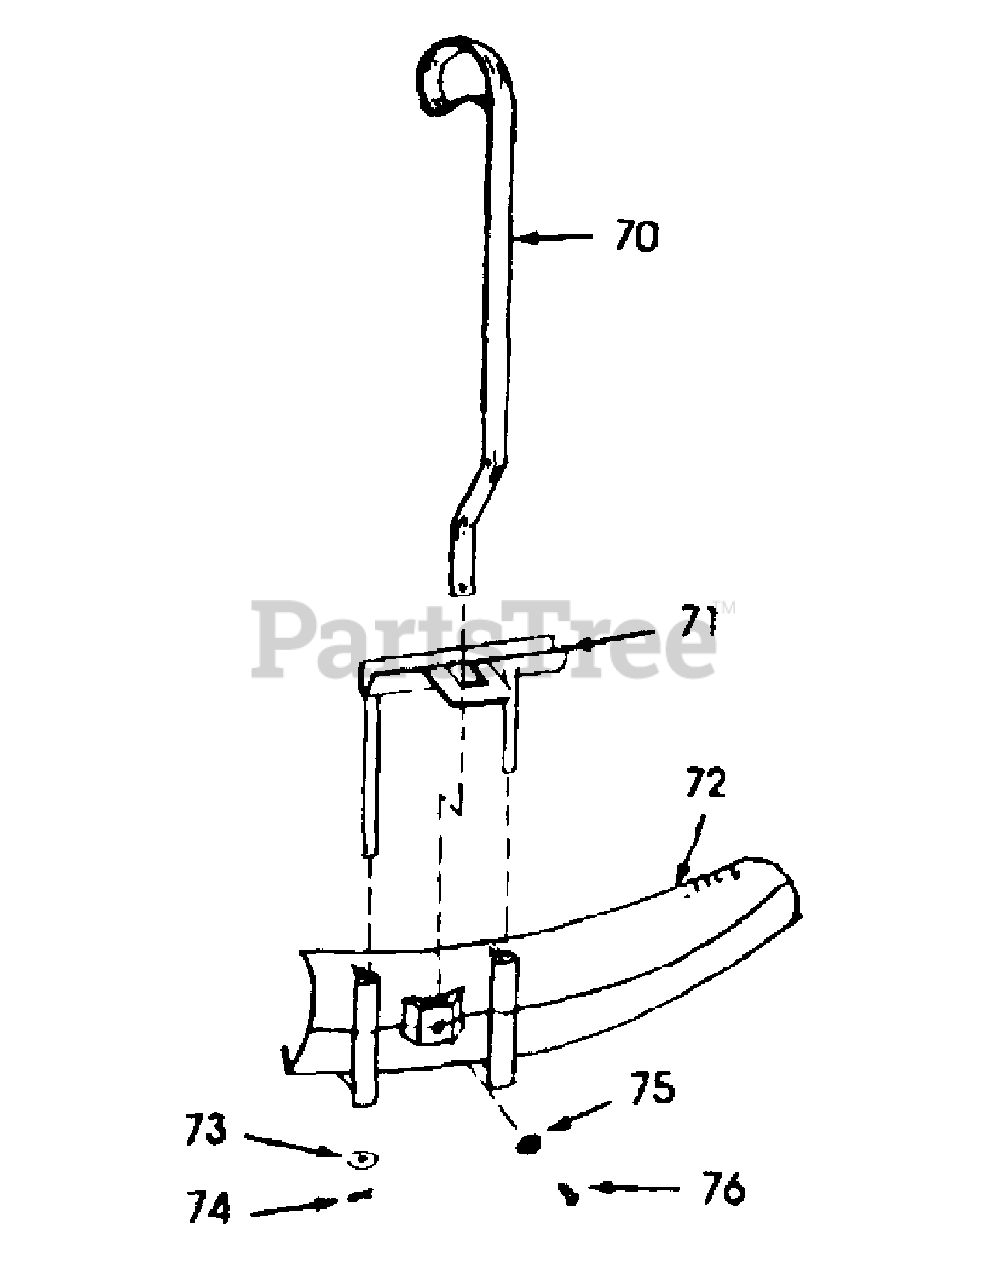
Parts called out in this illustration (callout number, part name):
70	SS Handle
71	SS Bracket
72	Deflector
73	SS Washer
74	SS Cotter Pin
75	SS Ext. Tooth Washer
76	SS Machine Screw
